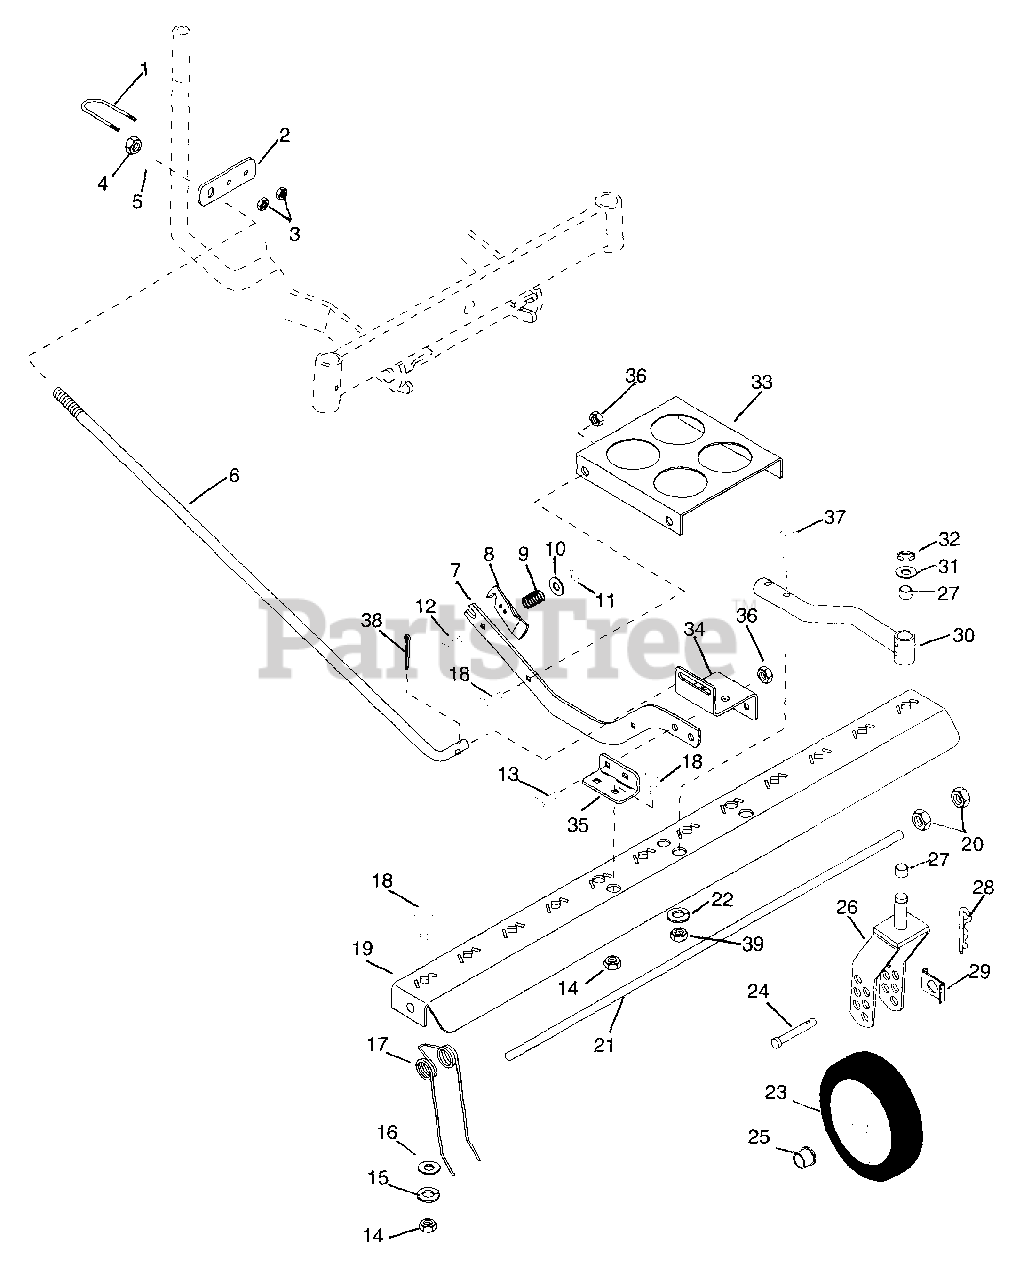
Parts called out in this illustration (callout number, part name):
2	LIFT HANDLE BRACKET
3	NUT-HEX .250-20 PL
4	NUT-LK-NYL .375-16 PL
5	WSHR-LK .250X.077 HVY PL
6	LIFT ROD
7	LIFT ARM
8	AXLE LOCK
9	SG-COMP .058X.68X.75
10	WSHR-FL-STL.281X.62X.065 PL
11	NUT-LK-CTR .250-20 PL
12	BLT-RDHDSQNK .25-20X1.50 PL BL
13	BLT-RDHDSQNK .31-18X.88 SHTPL
14	NUT-HEX .312-18
15	WSHR-LK .312X.097 PL HVY
16	WSHR-FL-STL .328X1.0X.094 PL
18	BLT-RDHDSQNK .31-18X.75 SHT PL
19	CHANNEL
20	NUT-LK-FLG .250-20 PL
22	WSHR-LK .375X.115 HVY PL
23	WHEEL
24	PIN-CLEV .494X2.62 YWZC
25	BSHG-FLG .500X.625X.500X.750
26	WHEEL YOKE WELDMENT
27	BSHG-SLV .500X.625X.500
28	PIN-HAIR INT .14X.4X2.75
29	AXLE TAB
30	WHEEL BRACKET WELDMENT
31	WSHR-FL-STL .505X.880X.072 PL
32	RG-RTNG-EXT .438X.035
34	LIFT BRACKET
35	LIFT BRACKET
36	NUT-LK-NYL.312-18 PL
37	BLT-HEX .38-16X1.75 PL GR2
38	PIN-COTR .12X.75 PL
39	NUT-HEX .375-16
